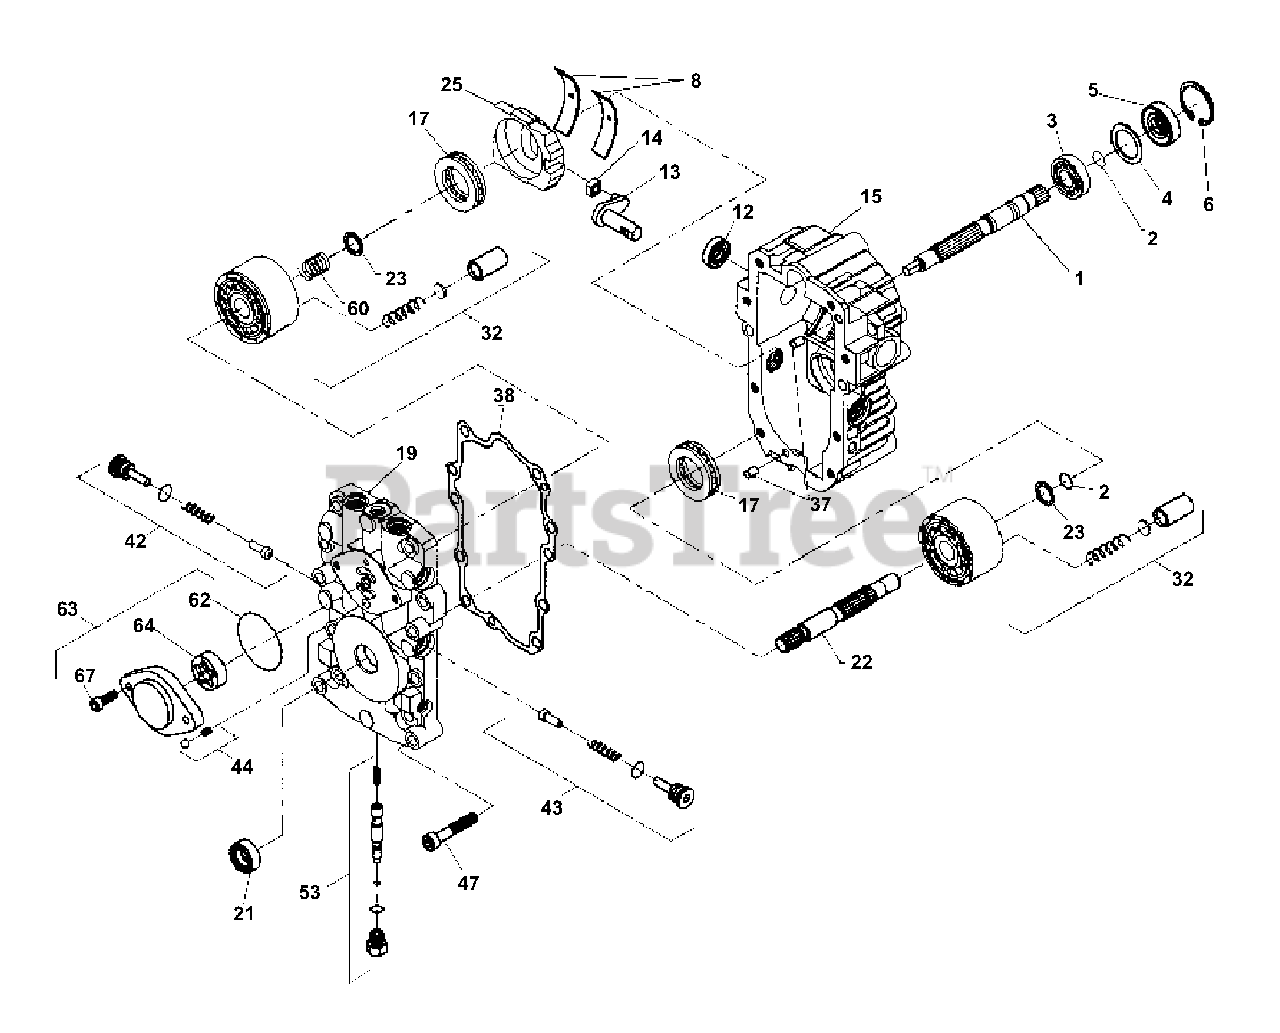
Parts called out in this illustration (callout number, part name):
1	Shaft, Pump
2	Ring, Retaining
3	Bearing, Ball
5	Seal, Lip
6	Ring, Retaining
8	Bearing, Cradle
13	Arm, Trunnion
14	Guide, Slot
15	Housing Kit, Transmission
17	Bearing, Thrust, Ball
19	Center Section Kit
22	Shaft, Motor
23	Washer, Block Thrust
25	Swashplate, Variable
32	Block Assembly
37	Pin, Stainless, Headless
38	Gasket, Center Section
42	Check Valve Kit
43	Check Valve Kit
44	Charge Relief Kit
47	Screw, Socket Head, Cap
53	Bypass Valve Kit
60	Block Spring
63	Charge Pump Kit
64	Gerotor Assembly
67	Screw, Socket Head, Cap
